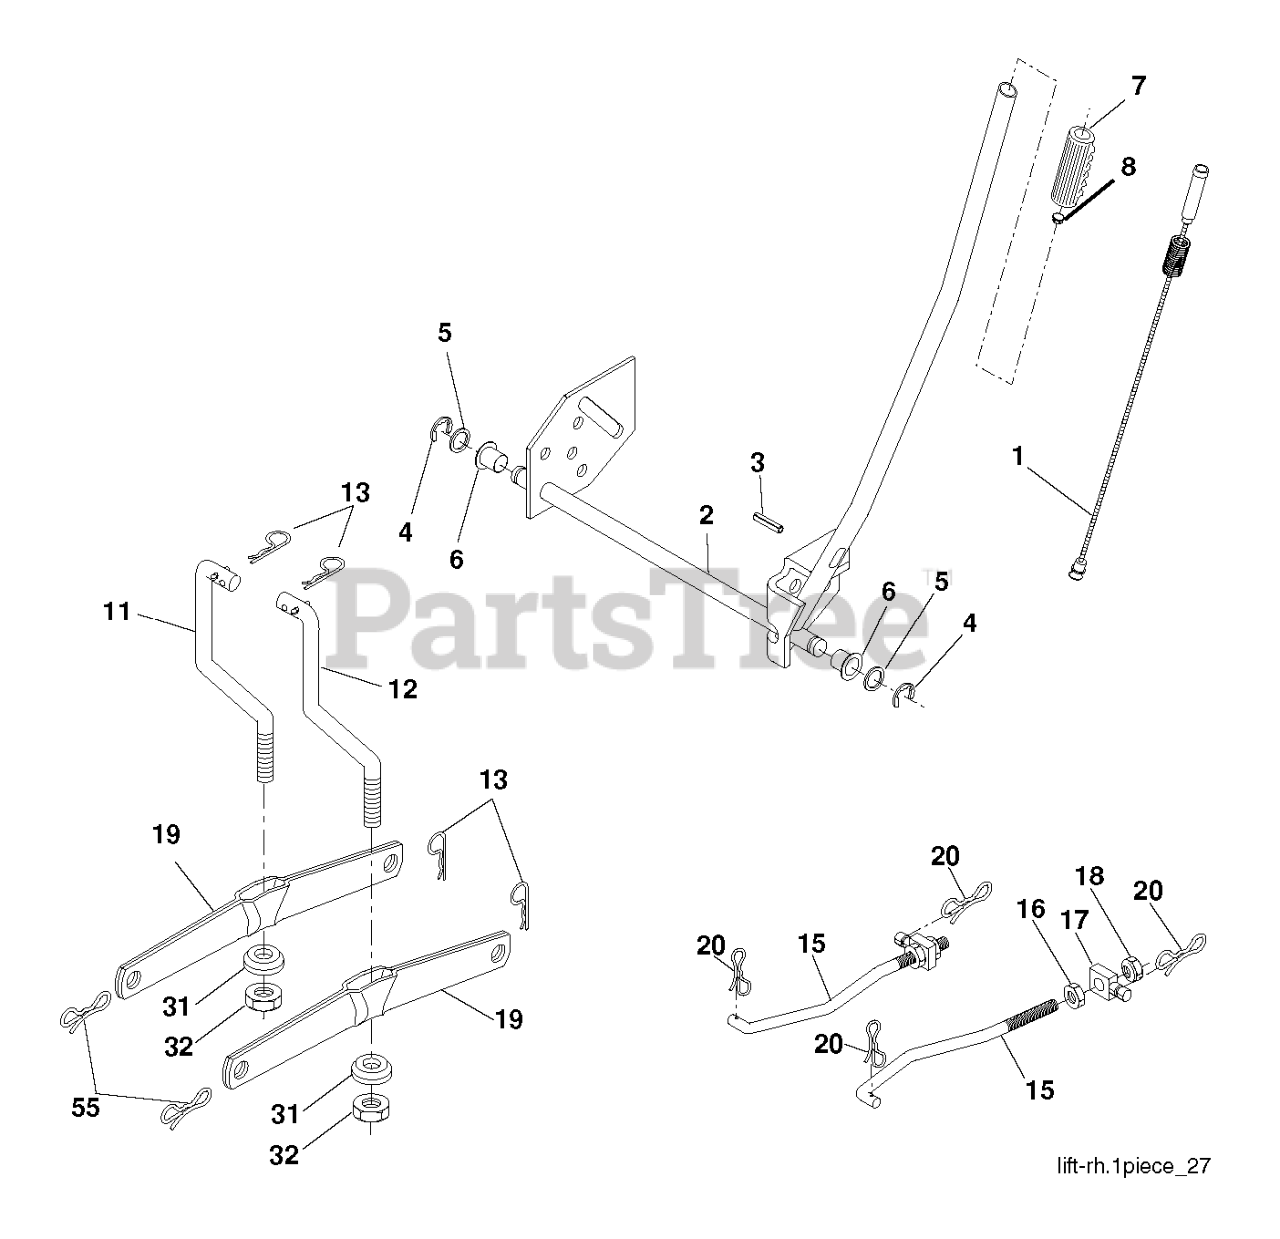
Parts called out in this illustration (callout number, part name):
1	PLUNGER.ASM.LIFT.LVR.BLK.17.32
2	SHAFT ASM R HANDLE
3	PIN GROOVE.
4	RETAINING RING LT
6	BEARING.NYLON
8	PLUNGER BUT KIT
11	LINK LIFT LH
12	LINK LIFT RH
13	RETAINER-SPRNG RB
15	LINK.SUSPENSION.FRONT
16	NUT.HEX.JAM.1/2-13
18	NUT.LK.W/WSH.1/2.
19	ARM.REAR.SUSPENSION
20	PIN.COTTER.7/16.BOW TI.
31	BEARING.PIVOT.LIFT
32	NUT CROWNLOCK 3/8-24
55	PIN.COTTER.5/16.BOW TI
